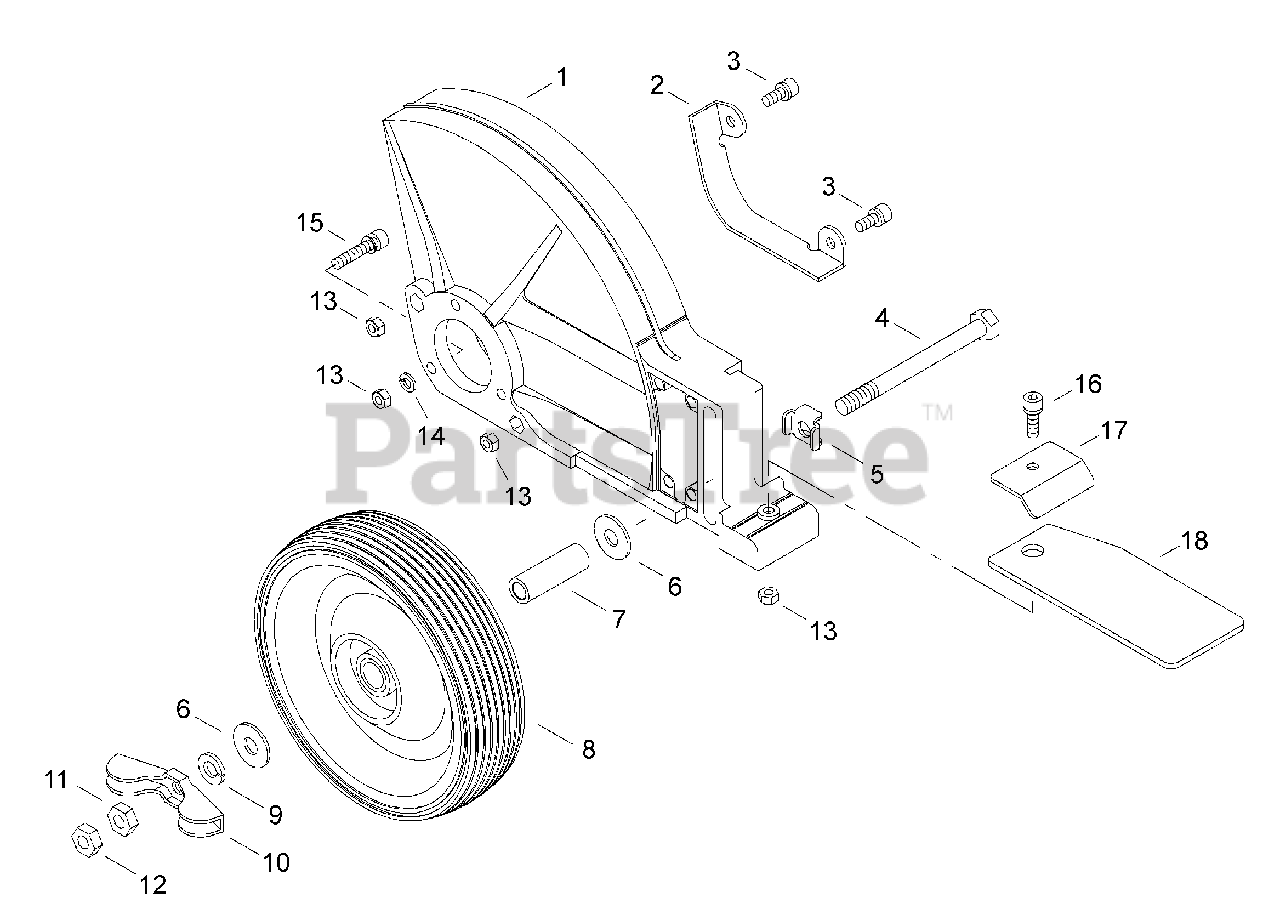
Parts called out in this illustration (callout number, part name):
1	SHIELD, DEBRIS
2	PROTECTOR
3	SCREW - 5X12
4	BOLT - 8X90
5	BRACKET
6	WASHER
7	COLLAR
8	WHEEL
9	LOCKWASHER - 8
10	WINGNUT
11	NUT - 8
12	LOCKNUT
14	LOCKWASHER - 5
15	SCREW - 5X25
16	SCREW - 5X16
17	PLATE
18	DEFLECTOR
